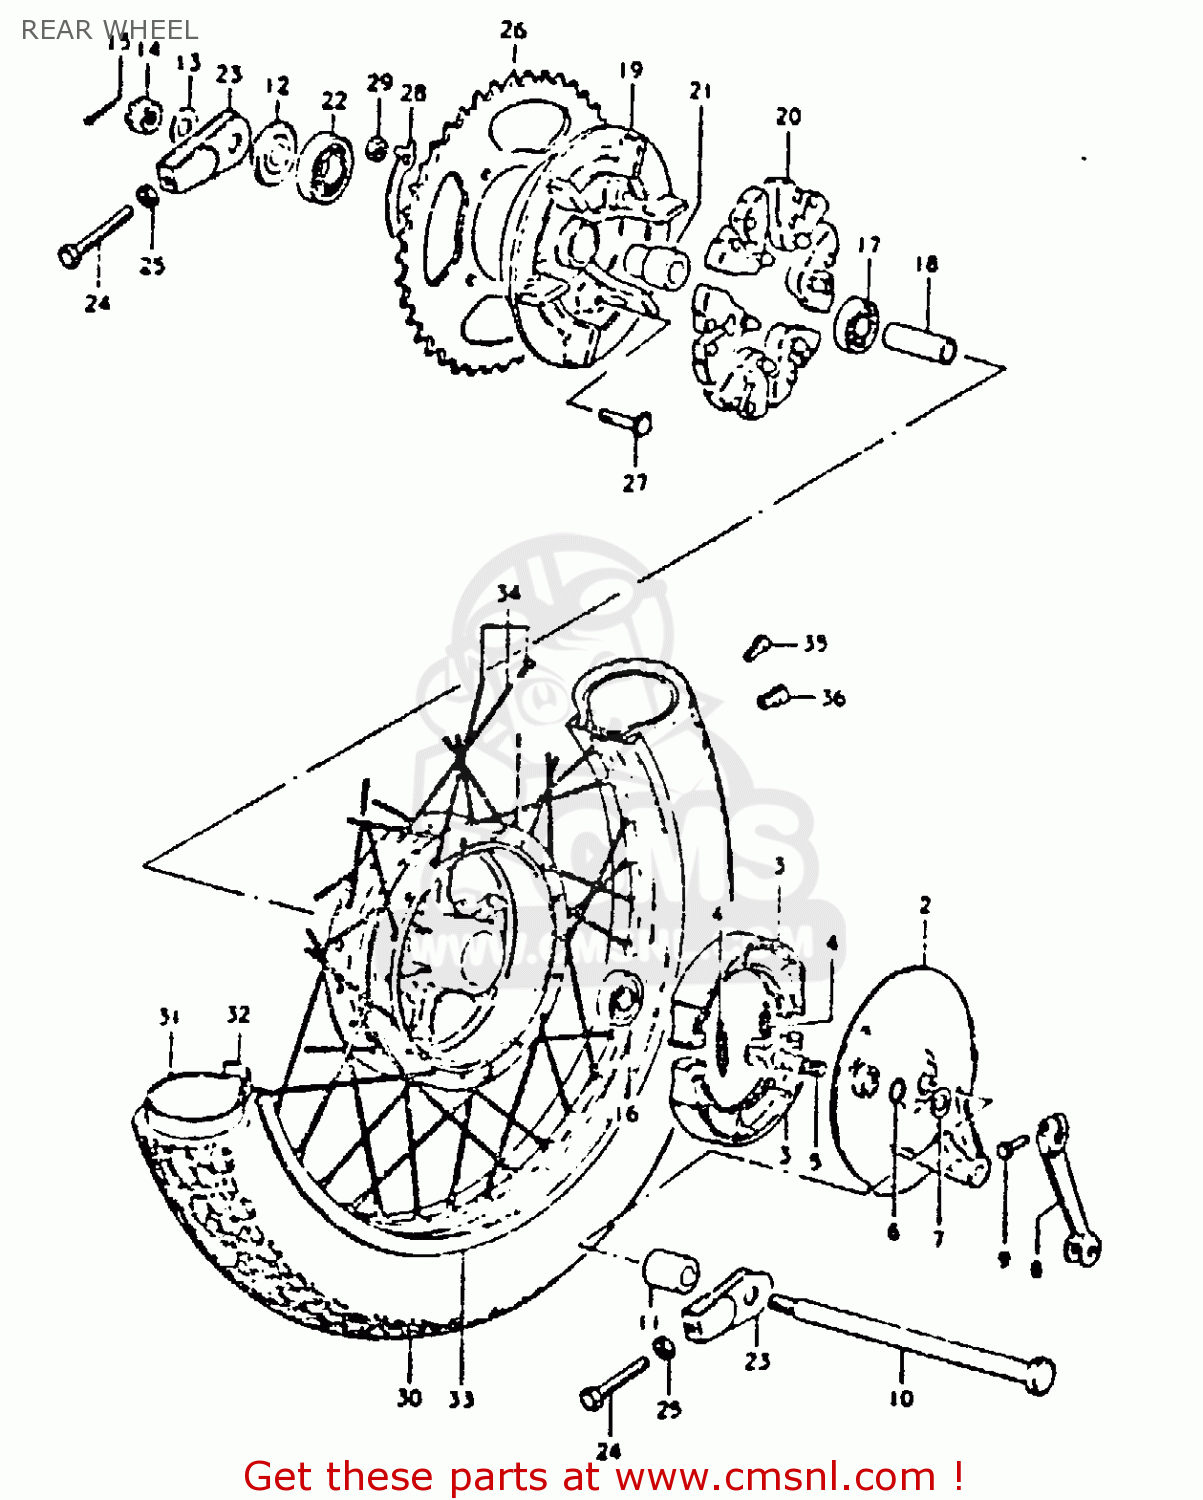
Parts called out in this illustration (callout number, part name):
1	HUB,RR
2	PANEL,REAR HUB
3	SHOE,BRAKE
4	SPRING,BRAKE SHOE
5	CAM,FRONT BRAKE
6	O-RING,BOSS
7	WASHER (15X24X1.6)
8	LEVER,RR BRAKE CAM
9	BOLT
10	AXLE,REAR
11	SPACER
12	SPACER,REAR AXLE,LEFT
13	WASHER
14	NUT
15	COTTER PIN
16	BEARING, RH
17	BEARING
18	SPACER(15.3X21.7X58)
19	DRUM,REAR SPROCKET MOUNT
20	ABSORBER,RR HUB SHOCK
21	RETAINER,RR SPROCKET MTG
22	BEARING
23	ADJUSTER,CHAIN,R
24	BOLT
25	NUT
26	SPROCKET,RR(NT:47)
27	BOLT(8X33.5)
28	WASHER,LOCK
29	NUT (8MM)
30	TIRE
31	TUBE 3.50-17 089-432MM
32	PROTECTOR,WHEEL,INNER
33	RIM,REAR WHEEL
34	SPOKE ASSY,RR
35	BALANCER,WHEEL (B)
36	BALANCER,WHEEL (30G)
